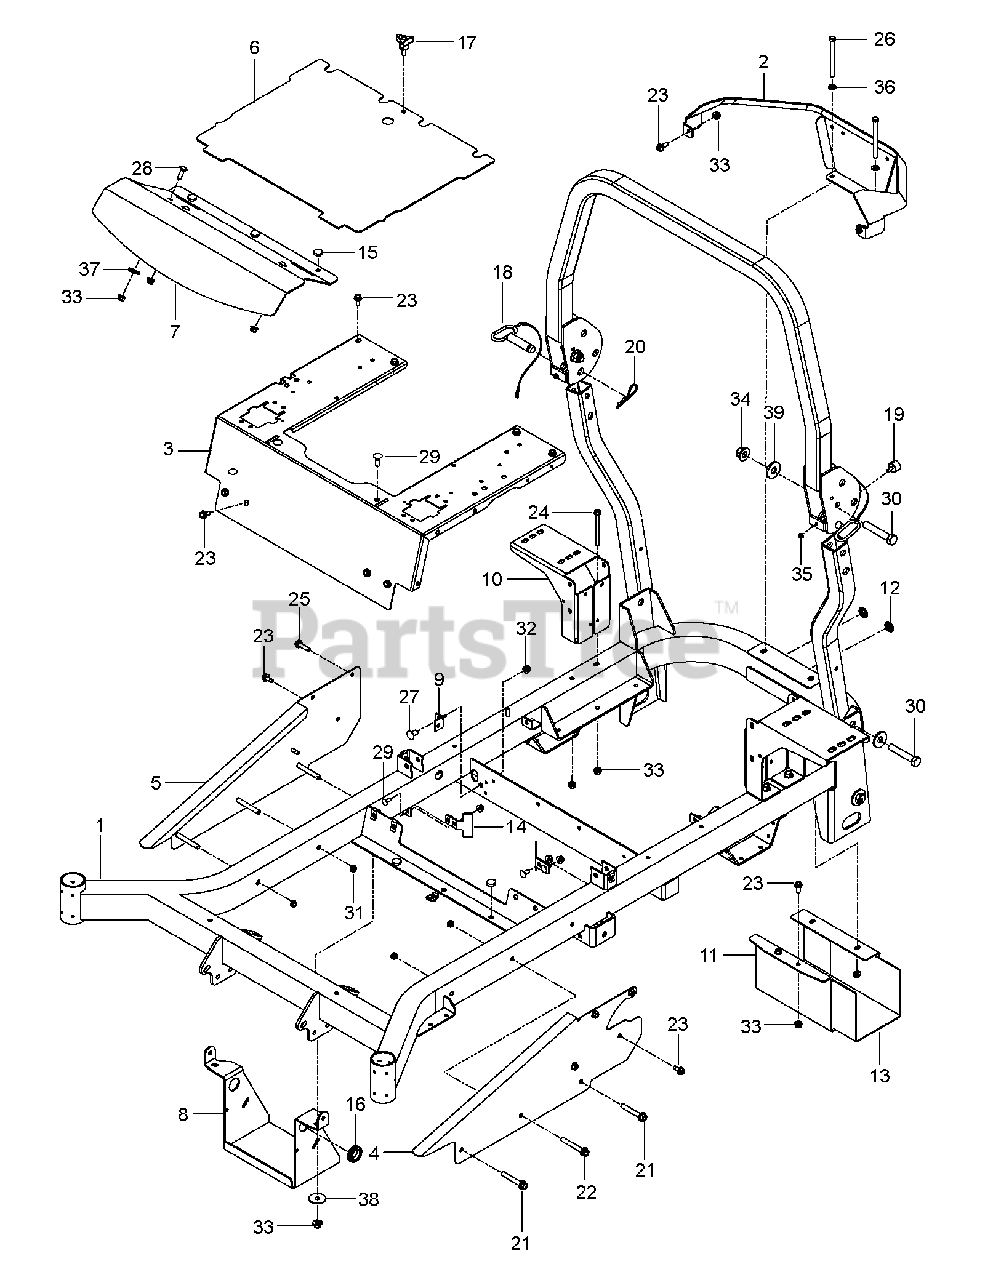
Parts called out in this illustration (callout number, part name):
1	KIT.FRAME.W/DECALS.X668
2	GUARD.PNT.REAR.MZ.GRAY
3	SUPPORT.PNT.SEAT.CONTROL.ORNG
4	SIDE.LT.ORANGE
5	SIDE.RT.ORANGE
6	PLATE, FLOOR W/DECALS
7	PLATE, FOOTREST
8	BRACKET.PNT.BATTERY.BLK
9	BRACKET.DAMPENER.BLACK
10	MOUNT, TANK, ZT BLK
11	SHIELD.MUFFLER.BLACK
12	CAP.PLUG.BP-1.BLACK
13	HEAT SHIELD
14	STOP, DECK, EZ+
15	GROMMET, BUMPER
16	RUBBER GROMMET
17	KNOB W/STUD
19	BUMPER, MALE STUD, 1/4-20
20	PIN HAIR .148 X 2-15/16 #210
21	HHFS 3/8-16 X 2.5 GR 5 ZD
22	HHFS 3/8-16 X 2-3/4 GR5 ZD
23	HHFS 5/16-18 X 3/4
24	BOLT.HEX.FLNG.5/16-18X3.75
25	HHFS 5/16-18 X 1.25 TPBLT GD 5
26	HCS 5/16C X 4
27	RHSNB 3/8-16 X 3/4 GR 5 BLK ZN
28	RHSNB 5/16C X 1
29	BOLT 5/16-18 X3/4 ZN/YEL GR 5
30	5/8-11 X 3-1/2 HHB GRADE 5
31	NUT HEX 3/8-16 NYLON, THIN
32	NUT 3/8-16 HEX FLG NYLOC ZD
33	5/16-18 NYLOC FLANGE NUT
34	NUT 5/8-11 FLG NYLOC ZD
35	RP_NUT 1/4-20 NYLOC
36	WASHER
37	WASHER 1/2" FLAT
38	WASHER.13/32X1-1/2X16GA
39	WASHER, 5/8 FLAT
